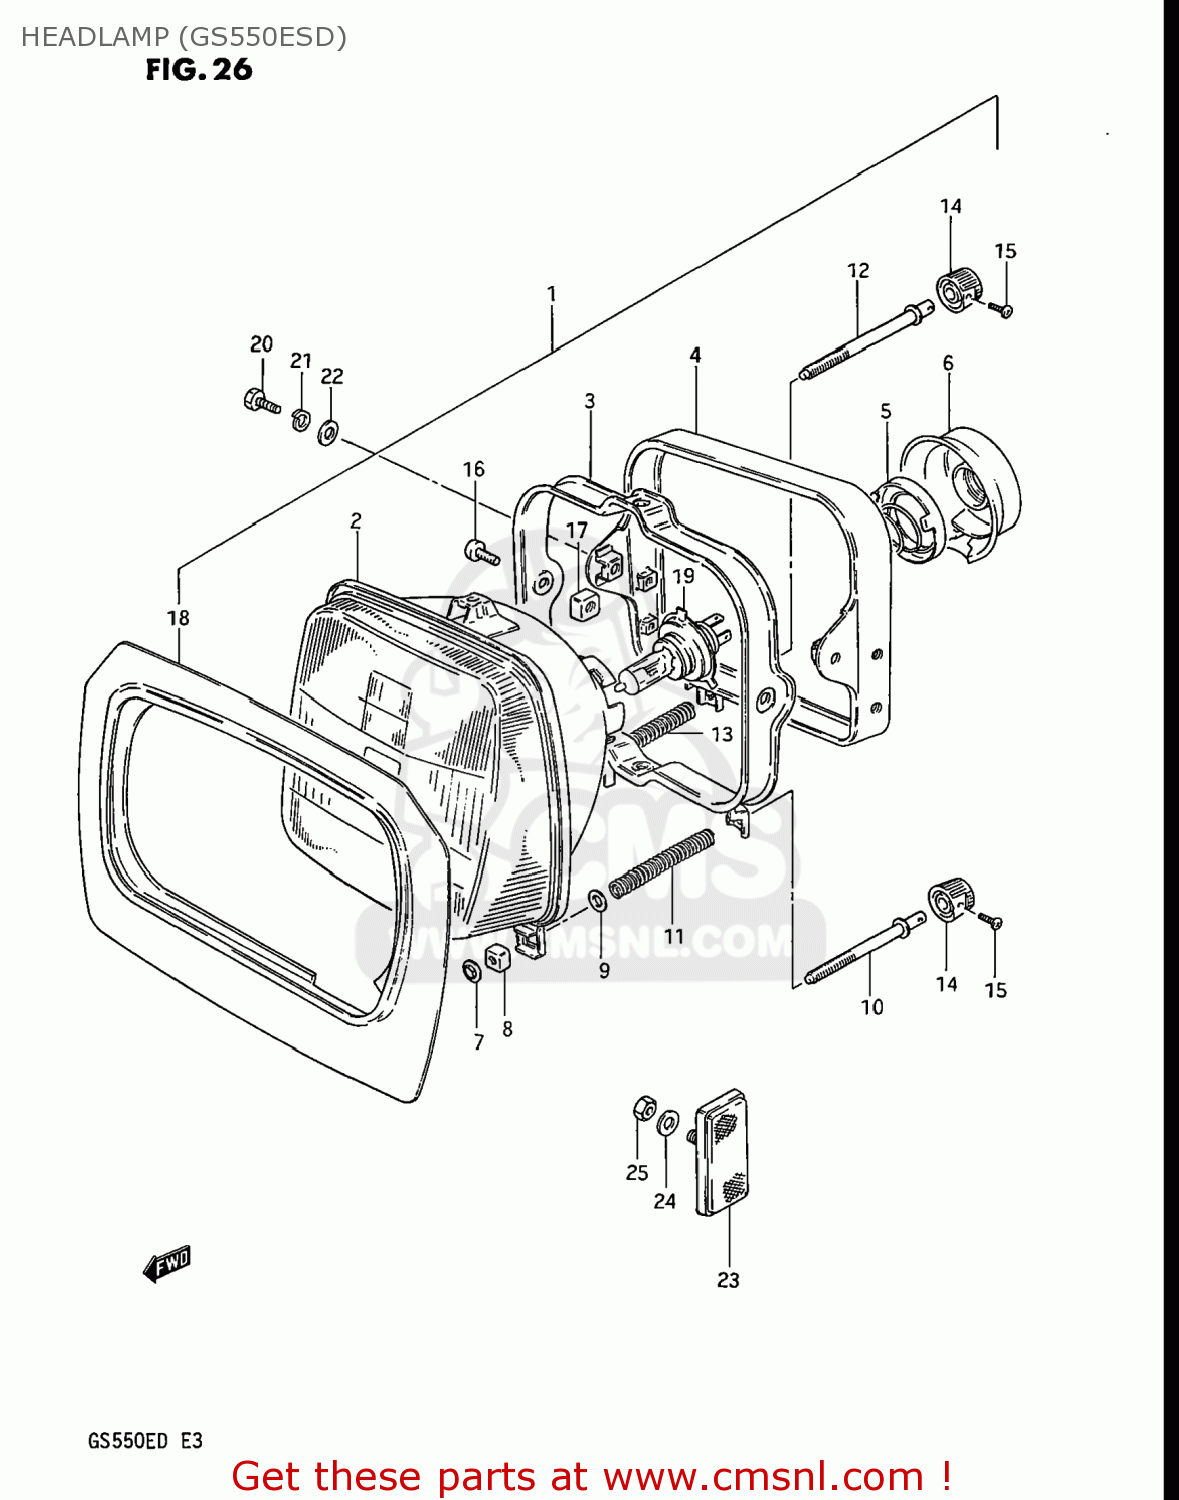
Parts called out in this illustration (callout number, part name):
1	LAMP ASSEMBLY,HEAD
2	LAMP UNIT
3	RING,MOUNTING
4	HOUSING,LAMP UNIT
5	HOLDER
6	COVER,HEADLAMP SOCKET
7	NUT,HEADLAMP ADJUSTER
8	NUT,HEADLAMP ADJUSTER
9	WASHER
10	SCREW,HEADLAMP ADJUST
11	SPRING
12	SCREW,ADJUSTING
13	SPRING
14	KNOB,ADJUSTER
15	SCREW
16	SCREW
17	NUT
18	SHADE
19	BULB(12V60/55W,H4)
20	BOLT
21	LOCK WASHER
22	WASHER
23	REFLEX REFLECTOR ASSEMBLY
24	WASHER
25	NUT
